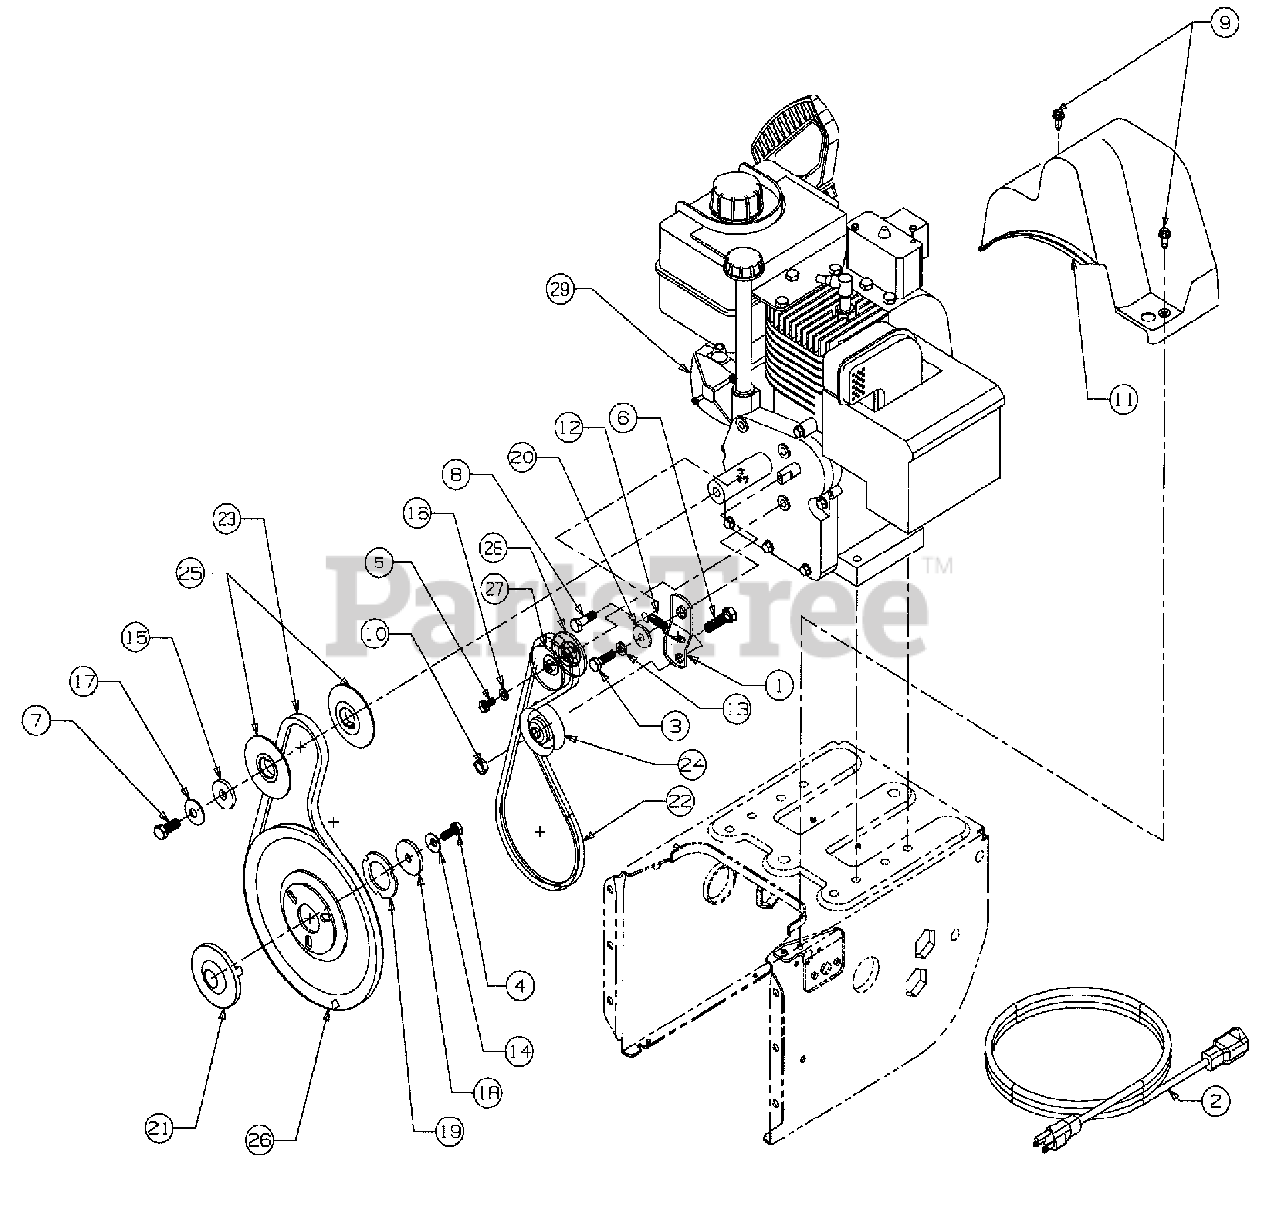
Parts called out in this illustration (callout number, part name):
3	Screw-Hex
4	Screw-Hex
5	Screw-Hex
6	Screw-Hex
7	Screw-Hex
8	Screw-Hex
9	Screw-Hex
10	Nut-Hex
11	Cover-Belt
12	Spring
13	Washer-Lock
14	Washer-Bell
15	Washer-Flat
16	Washer-Lock
17	Washer-Lock
18	Washer-Flat
19	Washer
20	Spacer
21	Adapter-Pulley
22	V-Belt
23	V-Belt
24	Idler-Flat
25	Pulley-Half
26	Pulley
27	Pulley-Half
28	Pulley-Half
29	Electric Start Kit
